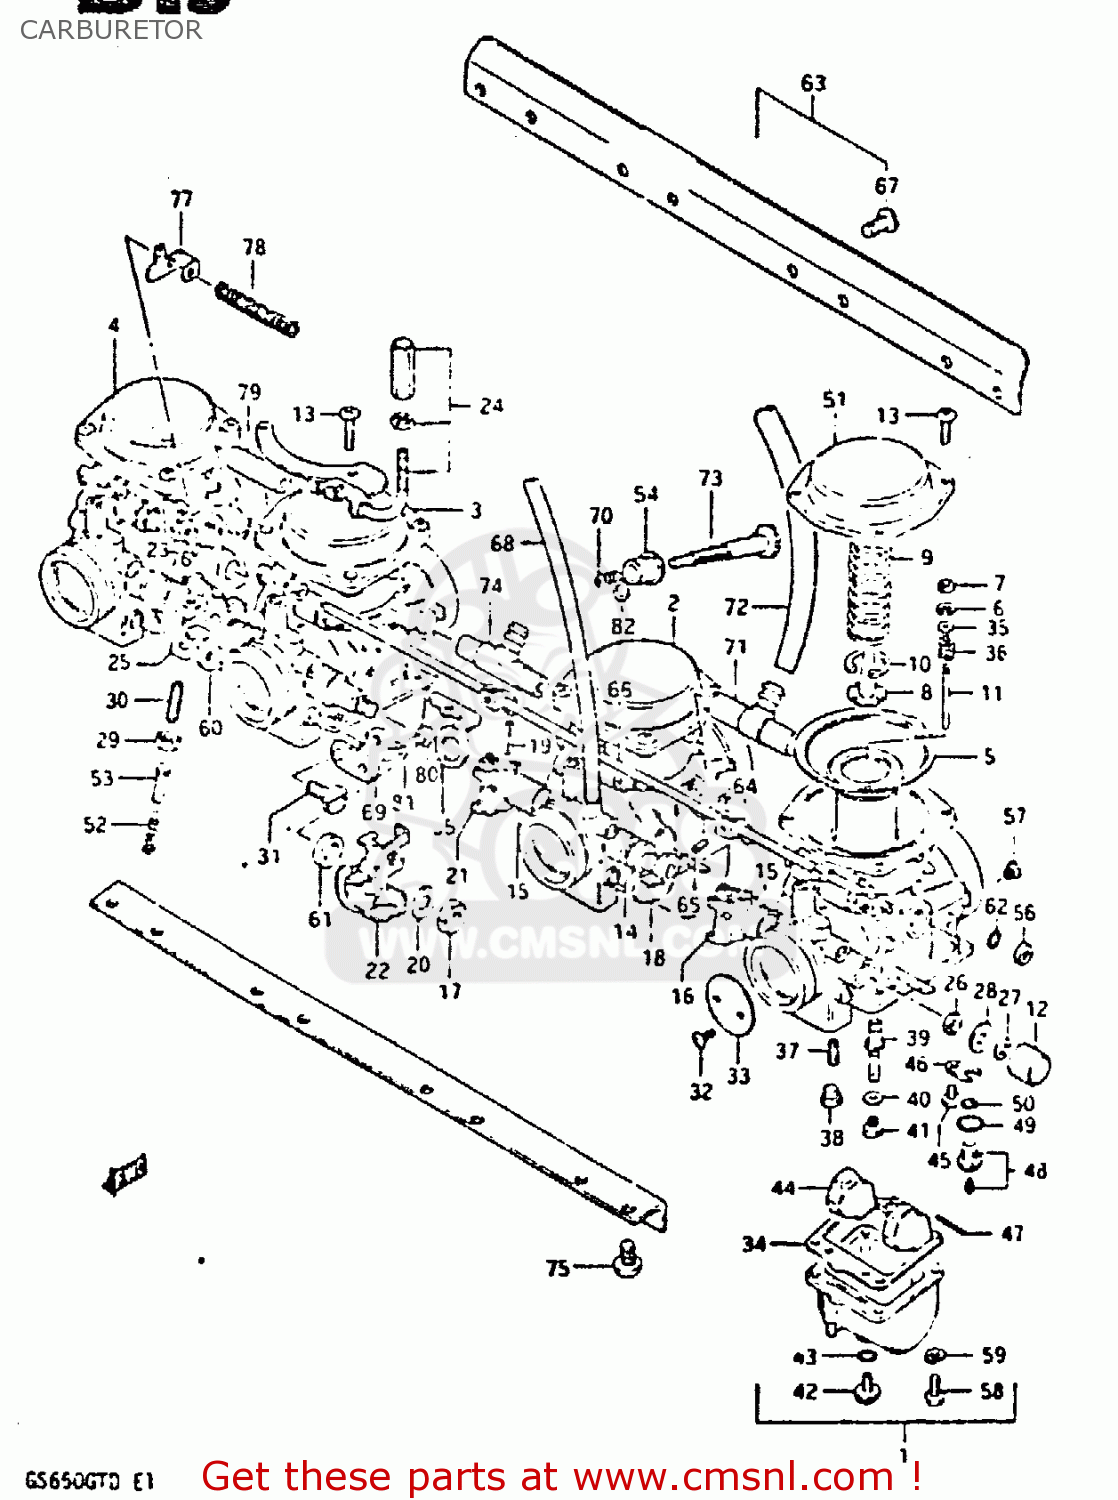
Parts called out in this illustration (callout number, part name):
1	CARBURETOR, LH
2	CARBURETOR, ML
3	CARBURETOR, MR
4	CARBURETOR, RH
5	DIAPHRAGM
6	CLIP,NEEDLE
7	RING
8	HOLDER,GUIDE
9	SPRING
10	E RING
11	NEEDLE, JET (5C41-3)
12	CAP
13	SCREW
14	GASKET,THROTTLE SHAFT (NAS)
15	SPRING,THROTTLE SHAFT
16	SHAFT,THROTTLE
17	NUT 8MM
18	SHAFT,THROTTLE
19	PIN,THROTTLE SHAFT
20	WASHER
21	LEVER,THROTTLE SHAFT
22	LEVER ASSEMBLY,THROTTLE
23	SPRING,THROTTLE SHAFT
24	BRACKET,THROTTLE CABLE
25	SHAFT,THROTTLE
26	SEAL
27	E RING
28	GASKET,THROTTLE SHAFT (NAS)
29	NUT
30	SCREW
31	SCREW
32	SCREW
33	VALVE,THROTTLE (BUTTERFLY)
34	GASKET,FLOAT CHAMBER (NAS)
35	WASHER
36	SPRING
37	JET,PILOT(42.5)
38	PLUG,NEEDLE JET
39	JET,NEEDLE
40	WASHER,NEEDLE NOZZLE
41	JET,MAIN(110)
42	PLUG,DRAIN
43	GASKET (NAS)
44	FLOAT
45	SCREW 4X6
46	PLATE,NEEDLE VALVE FITING
47	PIN,FLOAT
48	VALVE ASSEMBLY,NEEDLE
49	O-RING,NEEDLE VALVE
50	FILTER
51	COVER,DIAPHRAGM
52	SPRING,THROTTLE SCREW
53	PIN,THROTTLE LEVER
54	BUSH
55	BRACKET,THROTTLE ADJUST
56	CAP,STARTER VALVE
57	JET,AIR(140)
58	SCREW
59	LOCK WASHER
60	SHAFT,THROTTLE
61	WASHER
62	O RING
63	CARBURETOR ASSEMBLY
64	LEVER
65	SCREW
66	SHAFT,STARTER
67	SCREW
68	HOSE 4.5X8X390
69	BRACKET,THROTTLE ADJUST
70	SPRING
71	NIPPLE
72	HOSE
73	SCREW
74	NIPPLE,CARBURETOR
75	SCREW 6X12
76	LEVER,CHOKE CABLE
77	PLATE,CHOKE CABLE
78	SPRING,CHOKE CABLE
79	NIPPLE
80	SCREW
81	LOCK WASHER
82	WASHER
